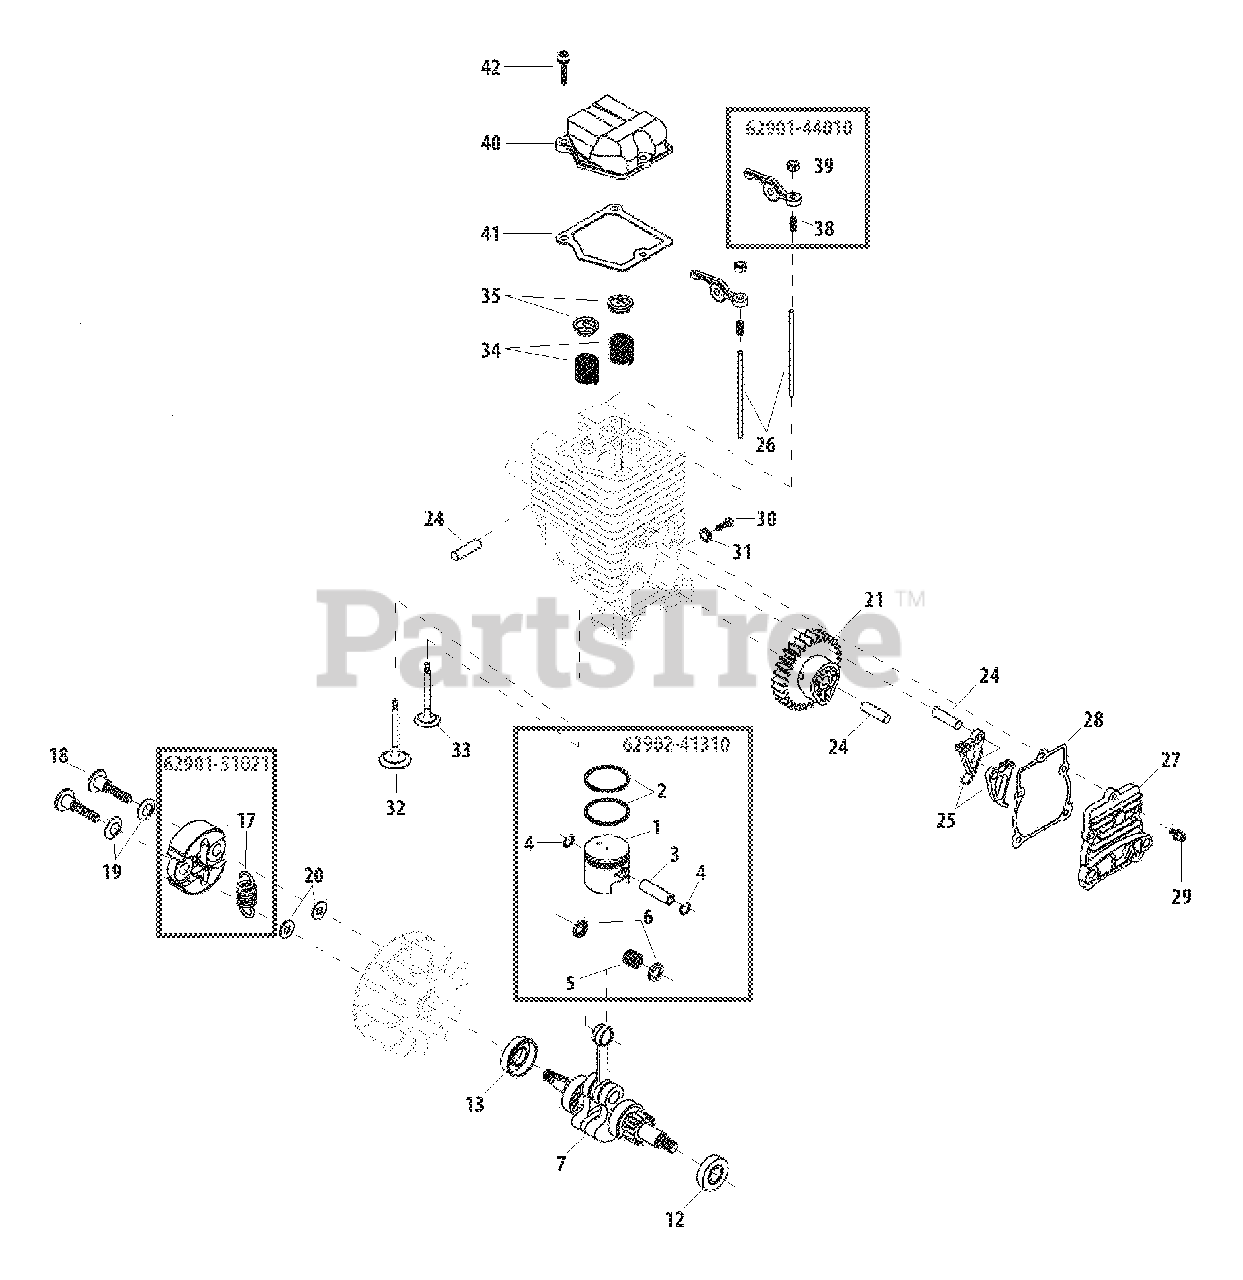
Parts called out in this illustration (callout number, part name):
1	PISTON
2	RING, PISTON
3	PIN, PISTON
4	RING, SNAP
5	BEARING, NEEDLE 9
6	WASHER, THRUST 9
7	CRANKSHAFT ASSY
12	SEAL, OIL 12
13	SEAL, OIL 12
17	SPRING, CLUTCH
18	BOLT, CLUTCH
19	WASHER, SPRING
20	WASHER 6 MM
21	GEAR, CAM
24	PIN, LOCATING Ø5×29.8 MM
25	FOLLOWER, CAM
26	PUSHROD
27	COVER, CAM GEAR
28	GASKET, CAM GEAR
29	BOLT M4×14
30	SCREW M5
31	WASHER Ø10ר5.5×2
32	VALVE, INTAKE
33	VALVE, EXHAUST
34	SPRING, VALVE
35	VALVE RETAINER ASSY
38	SCREW, ADJUSTER
39	LOCKNUT, ADJUSTER
40	COVER, ROCKER ARM
41	GASKET, ROCKER ARM
42	BOLT M4×12
62901-44010	ROCKER ARM ASSY
62901-51021	SHOE ASSY, CLUTCH
62902-41310	PISTON KIT
